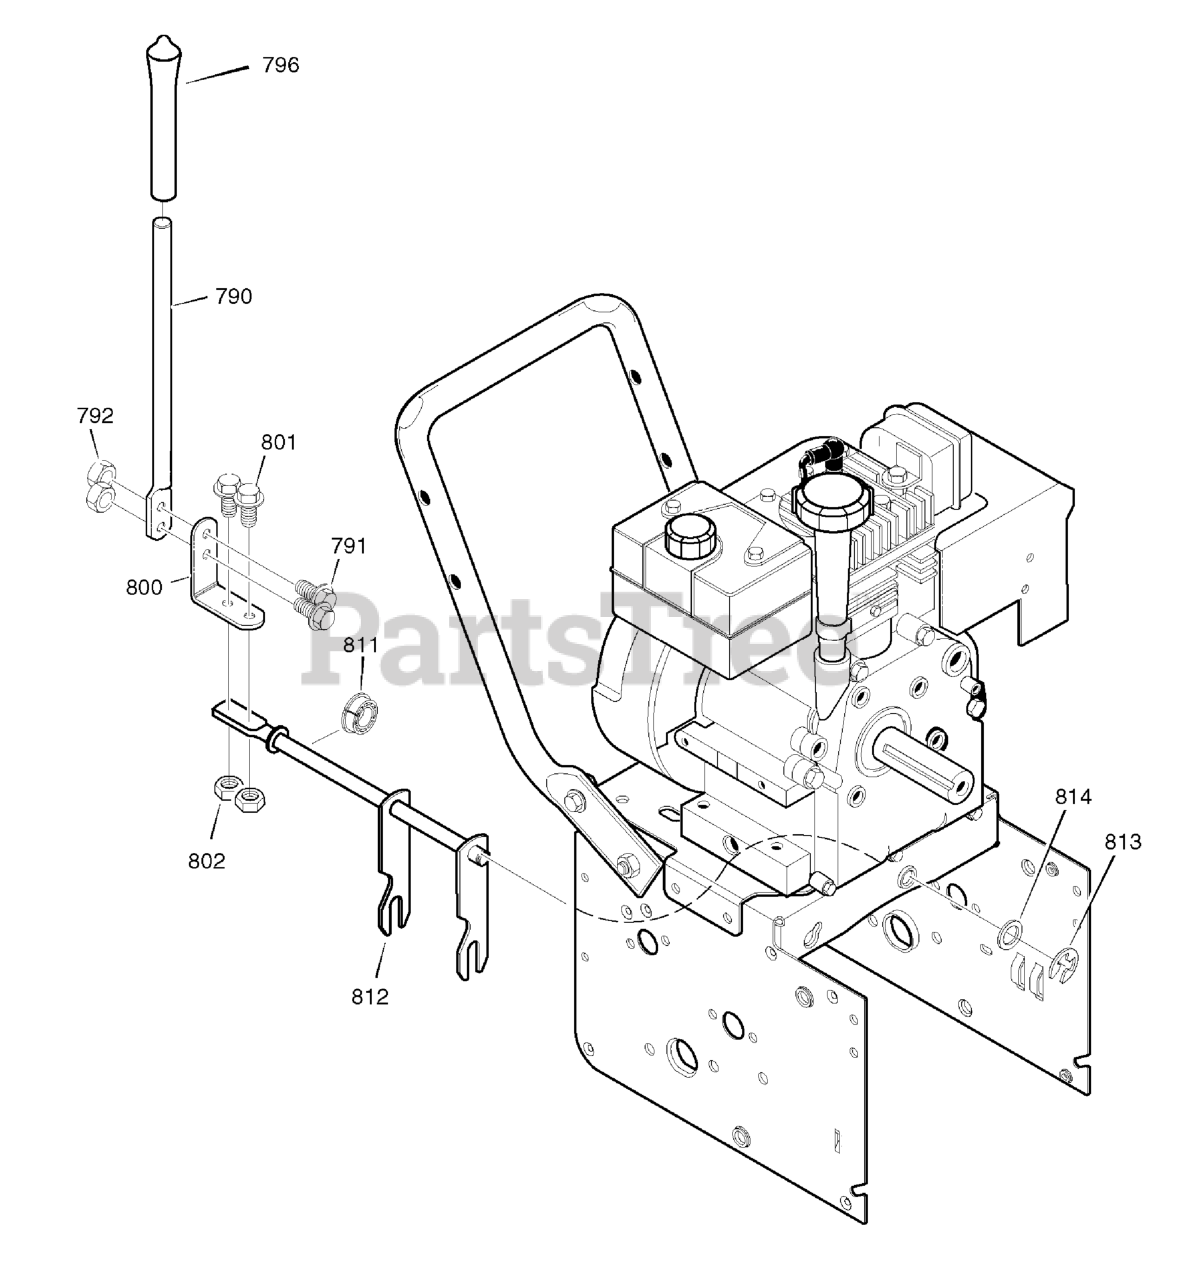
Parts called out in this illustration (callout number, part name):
790	ROD, Shift
791	SCREW, 1/4-20 x 3/4
792	NUT, 1/4-20
796	KNOB, Slip
800	LEVER, Spring
801	SCREW, 1/4-20 x 3/4
802	NUT, 1/4-20
811	BEARING, Flanged
812	ROD ASSEMBLY, Speed Select
813	RETAINER, Ring
